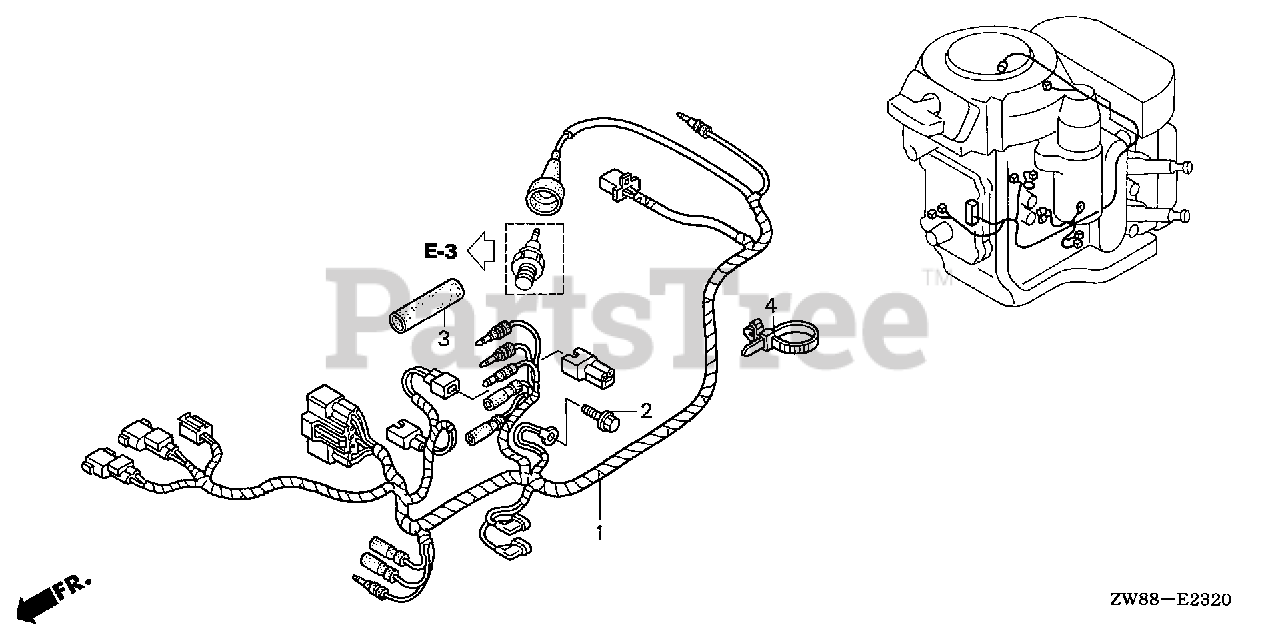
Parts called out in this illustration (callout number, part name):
1	WIRE HARNESS ASSY. (R/C PT)
2	BOLT, FLANGE (6X12)
3	TUBE, RUBBER (11.5X14.5)
4	BAND, WIRE (95MM)
